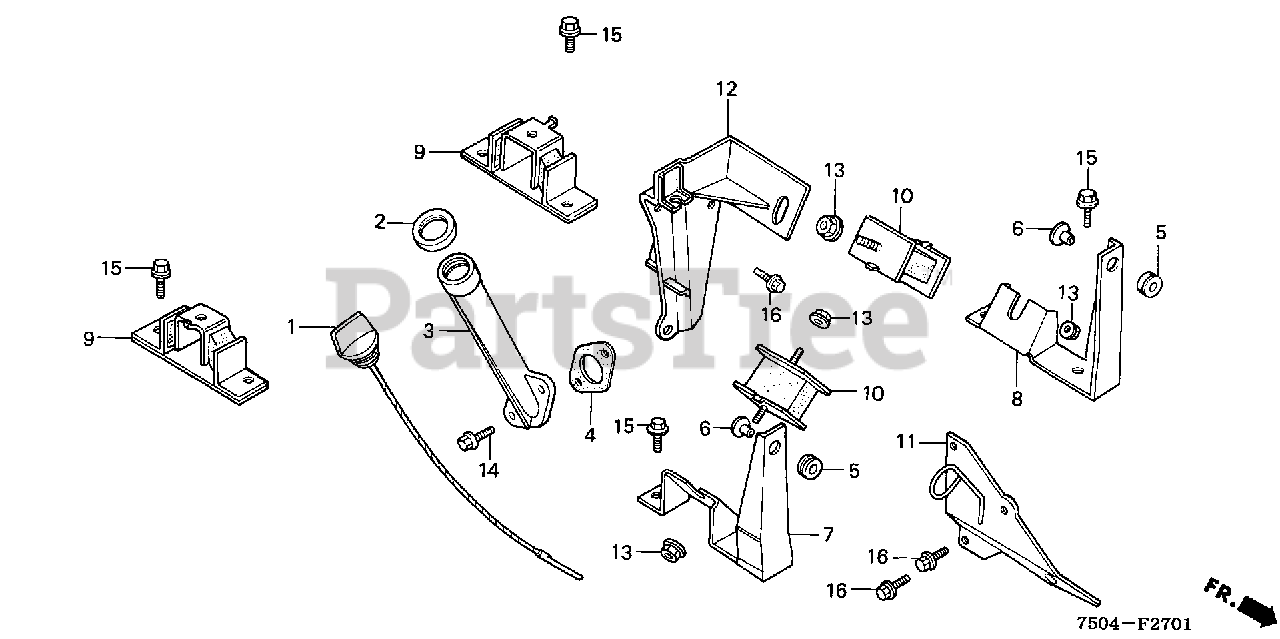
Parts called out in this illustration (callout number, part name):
1	CAP, OIL FILLER (NOT AVAILABLE)
2	GASKET, OIL FILLER CAP
3	PIPE, OIL FILLER
4	GASKET, OIL PIPE
5	RUBBER, RADIATOR SETTING
6	COLLAR, RADIATOR SETTING (NOT AVAILABLE)
7	STAY, R. RADIATOR
8	STAY, L. RADIATOR
9	RUBBER, ENGINE MOUNTING (NOT AVAILABLE)
10	RUBBER, ENGINE SETTING
11	BRACKET A, FR. ENGINE MOUNTING
12	BRACKET B, ENGINE MOUNTING
13	NUT, FLANGE (10MM)
14	BOLT, FLANGE (6X20)
15	BOLT, FLANGE (8X14)
16	BOLT, FLANGE (8X20)
